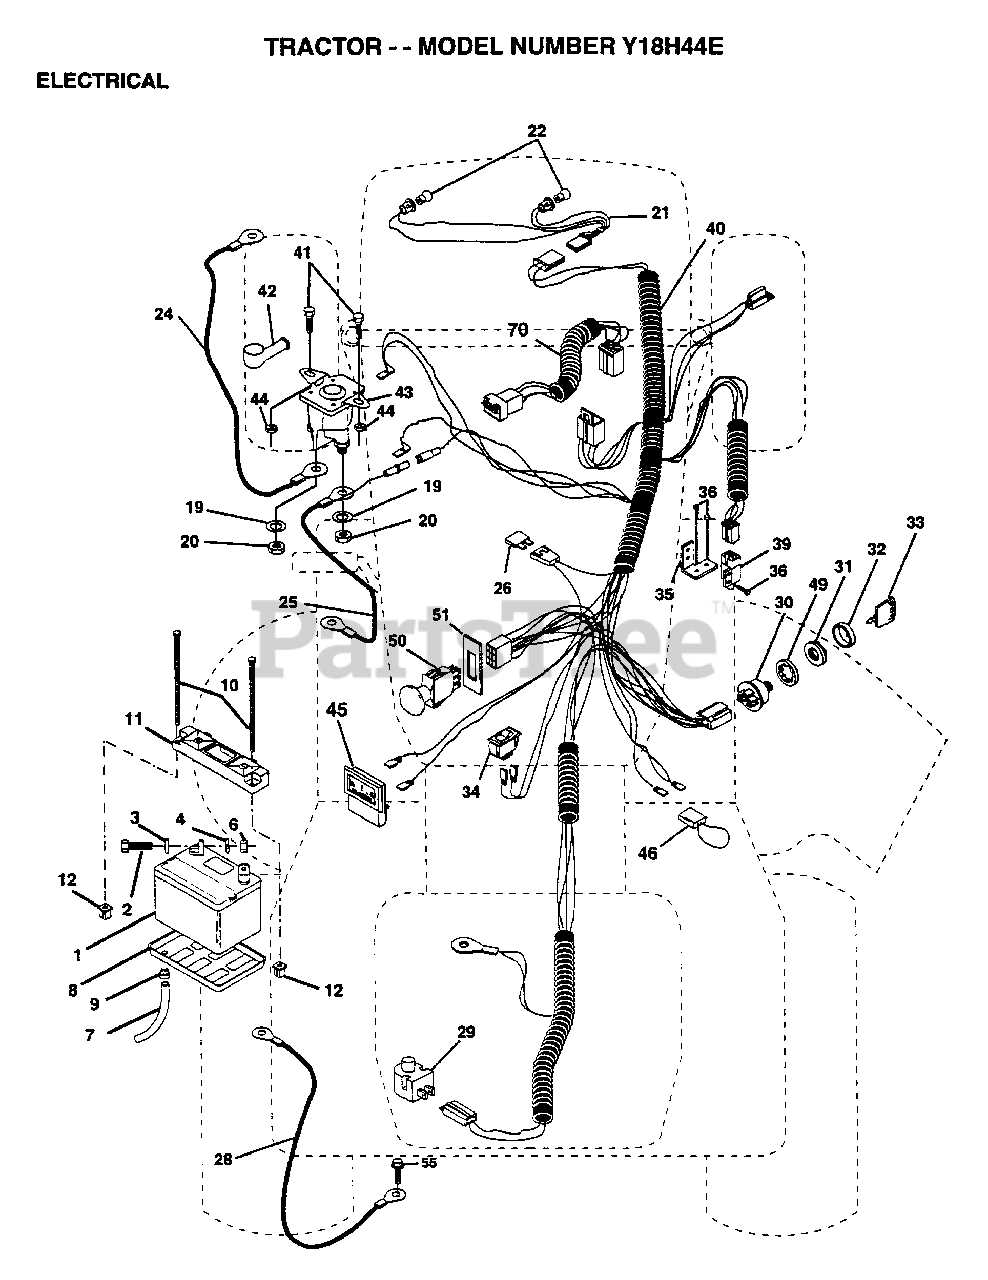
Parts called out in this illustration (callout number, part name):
2	BOLT LT
3	WASHER
4	LOCKWASHER
7	"DRAIN TU T, BATT"
8	"TRAY T, BATTERY"
9	HOSE CLAMP T
20	NUT
21	"HARNESS,LIGHT SOC"
22	HEADLAMP BULB
24	"CABLE T, BATTERY"
25	CABLE.6GA.22W/16W
26	FUSE HYT
28	CABLE.GRND.6GA.21
29	SWITCH SEAT
32	COVER KEY SWITCH
33	KEY MLD GEN DELTA
34	SWITCH LT
35	BRACKET LT
36	SCREW
39	SWITCH INTERLOCKT
40	HARNESS.ING.ELEC.
41	BOLT HXHD FIN
44	NUT
45	AMMETER
46	PROTECTION LOOP
49	LOCKWASHER
51	RING RETAIN PTO
55	SCREW LT
70	HARNESS.ENG.KOHL
